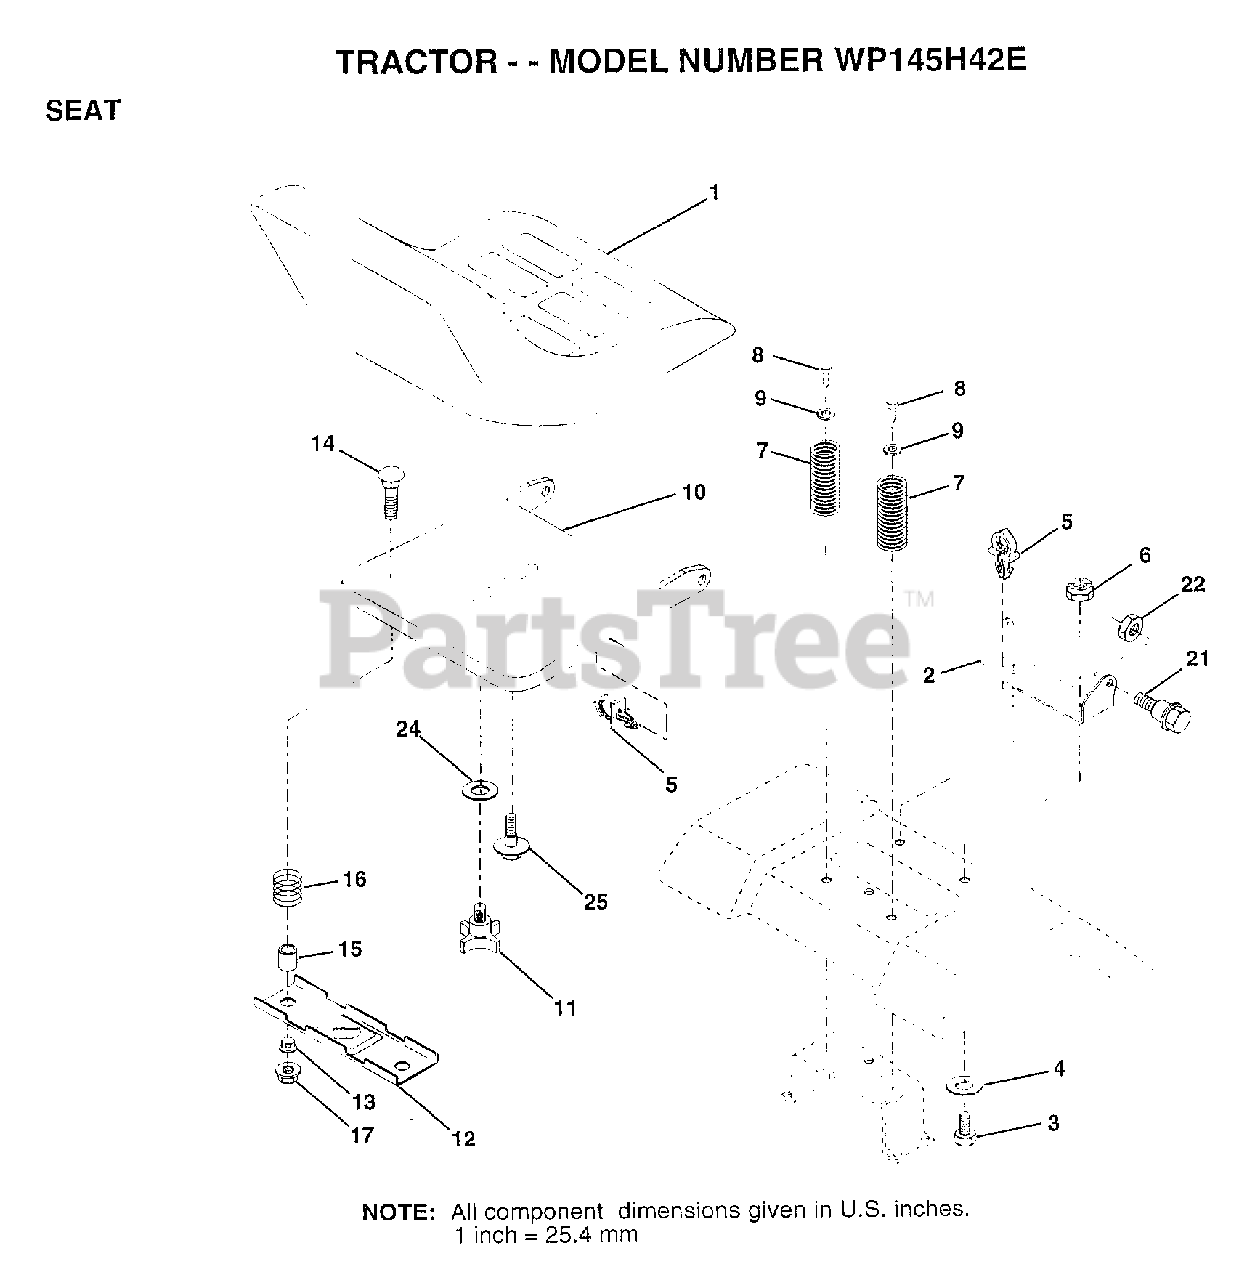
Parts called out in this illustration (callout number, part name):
2	BRACKET PVT SEAT
3	BOLT
4	WASHER PM
5	CLIP.PUSH-IN.HING
6	NUT
7	SPRING COMPRESSIO
8	SCREW GTV
9	WASHER
10	PAN-SEAT
11	"KNOB 1/2"" YT"
12	BRKT SWITCH
13	BUSHING
14	BOLT-RD HD SQ NK
15	SPACER SPLIT
16	SPRING COMPRESSED
21	"BOLT,SHOULDER"
24	WASHER
25	"BOLT,SHOULDER"
